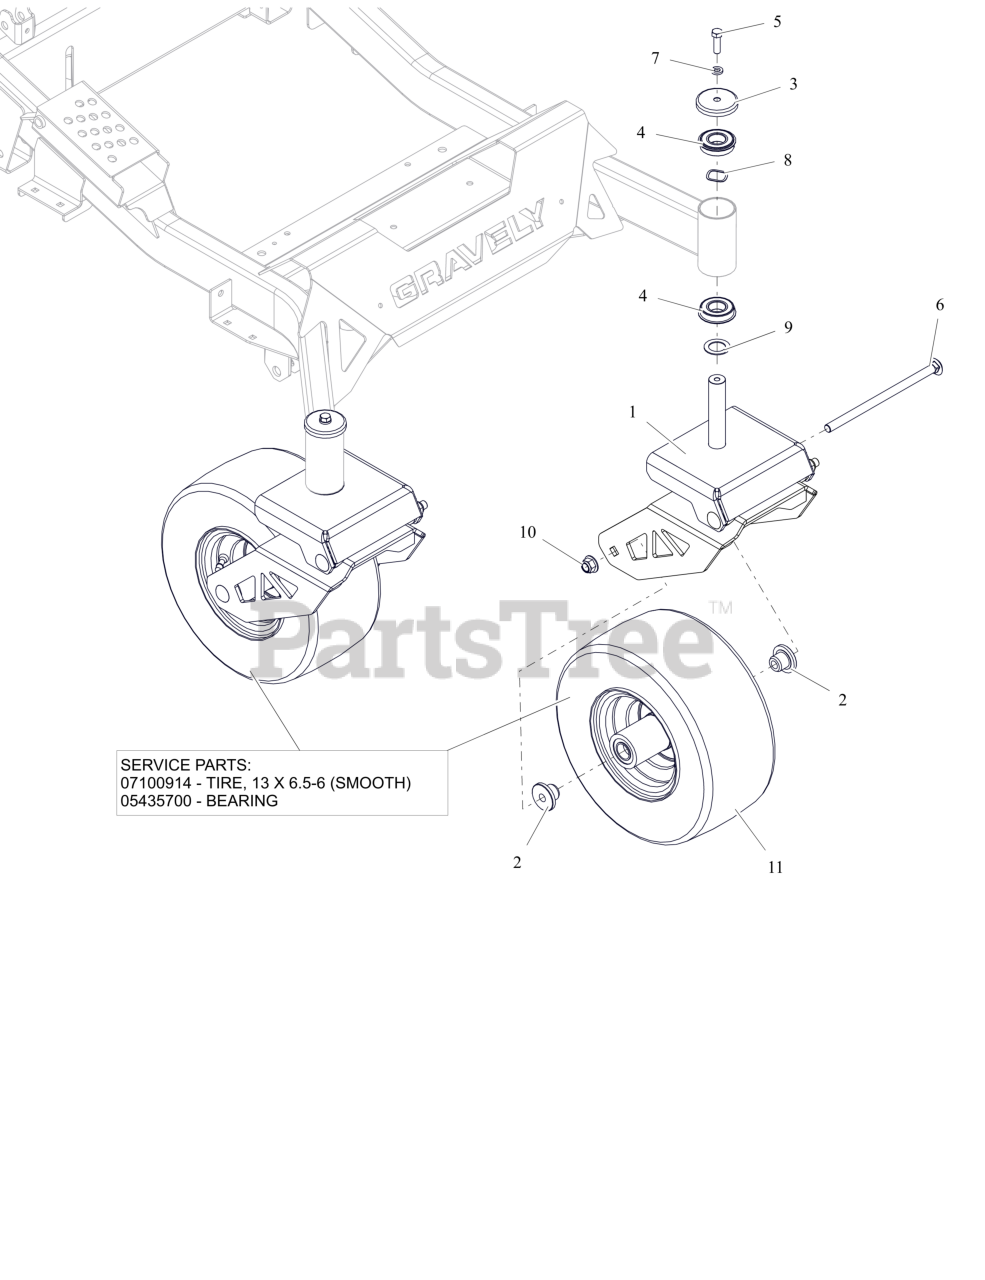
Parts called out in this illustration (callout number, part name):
1	ASM, SUSPENSION FORK
2	SPACER, FRONT WHEEL
3	SHIELD, AXLE BEARING
4	BEARING, BALL -2.000 OD X 1.000 ID X .5625 W/RING
5	BLT, HEX .38-16X1.25 G5 ZCC
6	BTL,RHSN .500-13 X 9 G5 ZCC
7	WSHR, LK-HVY .375X.115 ZCC
8	WSHR-WAVE 1.0X1.25X.028 .145FH
9	WSHR-HRD-THRS 1.007X1.542X.062
10	NUT,NYL-FLG .50-13 GF ZCC
11	ASM, WHL/TIRE 13X6.50-6
11	TIRE, 13X6.50-6 SMOOTH
11	BRG, 25MM ID X 52MM OD X 15MM
